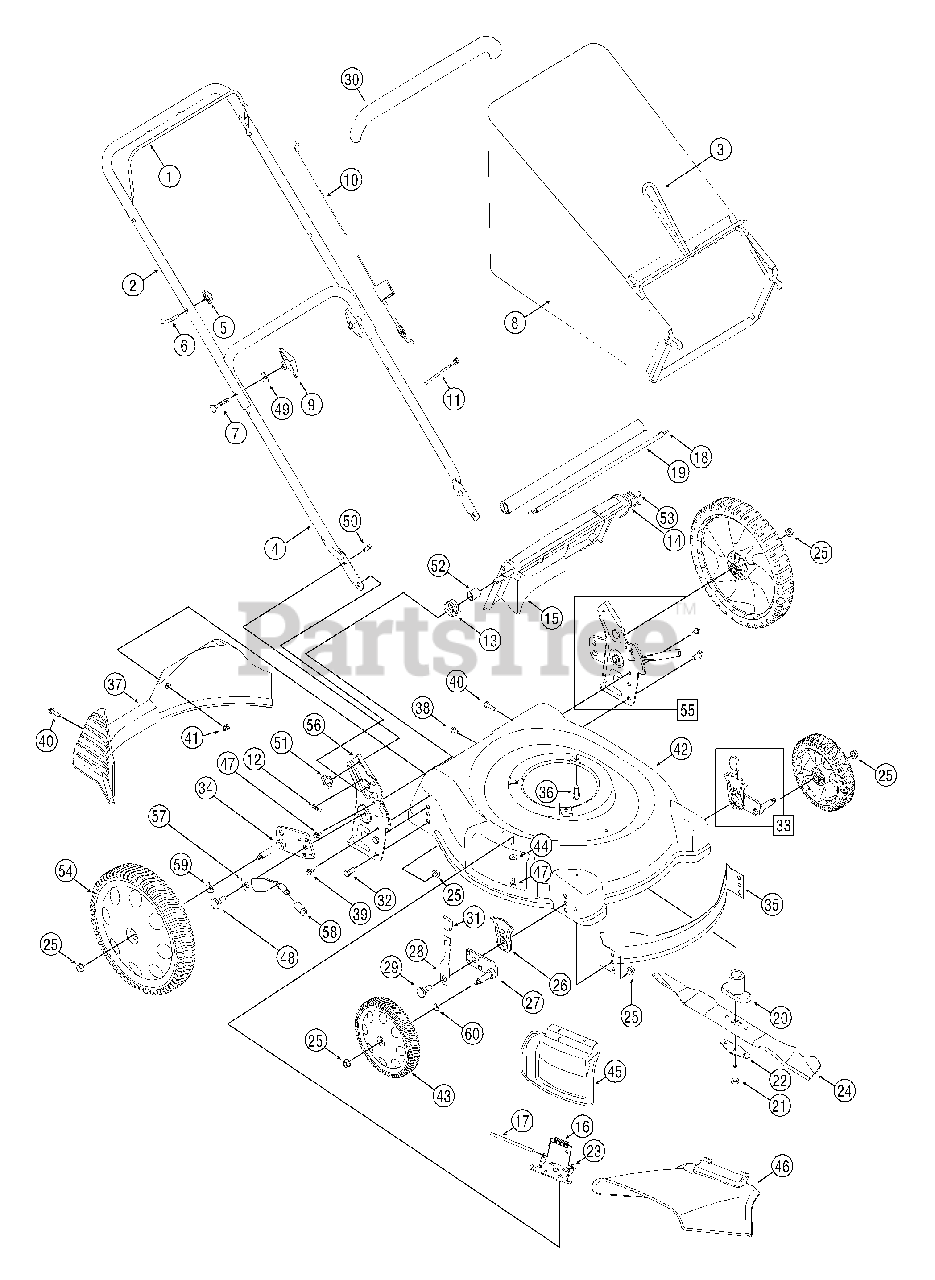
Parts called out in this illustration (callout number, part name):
1	Control Handle
6	Rope Guide
7	Carriage Bolt 5/16-18 x 2"
9	Wing Nut
10	Control Cable 40"
11	Cable Ties
12	Hairpin Clip
13	Torsion Spring - RH
14	Torsion Spring - LH
15	Grass Bag Door
16	Torsion Spring
18	Wire Rod
19	Trail shield
20	Blade Adapter
21	Hex Cap Screw 3/8-24 x 2.5
22	Blade Bell Support
23	Chute Deflector Adapter
24	21" Mulching Blade
25	Flange Lock Nut 3/8-16
26	Height Adjustment Plate
27	Pivot Arm Assembly - LH
27	Pivot Arm Assembly - RH
28	Spring Lever
29	Shoulder Screw
30	Deluxe Bail Cover
31	Spring Lever Knob
32	Hex Screw 3/8-16 x 0.75
33	Front Height Adjuster Assembly - RH
33	Front Height Adjuster Assembly - LH
34	Pivot Arm Assembly - RH
34	Pivot Arm Assembly - LH
35	Front Baffle
36	Hex Washer Screw 3/8-16 x 1.0
37	Rear Baffle 21" Rd.
38	Machined Screw 1/4-20
39	TT Screw 1/4-14 x .625
40	Hex Screw 1/4-15
41	Flange Lock Nut 1/4-20
44	Bell Washer.265 ID x.75 OD
45	Mulching Plug
46	Side Discharge Deflector
47	Screw 1/4-20 x.500
48	Hex Cap Screw 3/8-16 x 1.0
49	Shoulder Washer.320 ID x.930 OD
50	Hex Carriage Screw 1/4-20
52	Spacer.375 O.D. x.50 I.D. x 1.02"
53	Chute Door Pivot Rod
54	Rear Wheel 12x2.125 Gray IDL
55	Handle Bracket Assembly - RH
55	Handle Bracket Assembly - LH
56	Handle Bracket - RH
56	Handle Bracket - LH
57	Spring Lever
58	Spring Lever Grip
59	Spring Washer.500 x 1.00 x.022
60	Wave Washer.510 x.750 x.017
